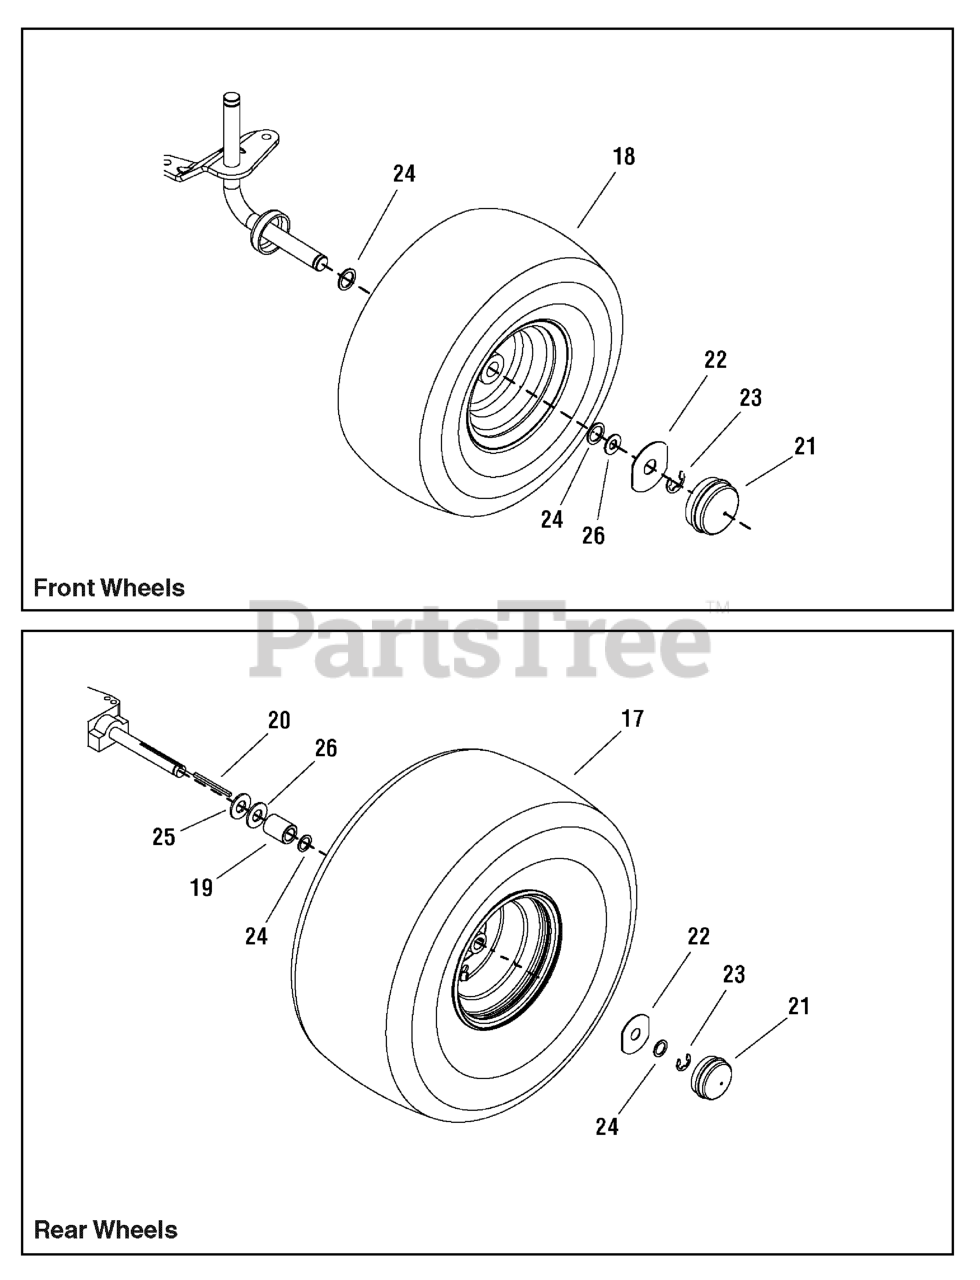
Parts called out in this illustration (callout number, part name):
17	WHEEL AND TIRE ASSEMBLY, Rear, 22 x 10 - 8
18	WHEEL AND TIRE ASSEMBLY, Front, 14.4 x 6
19	SPACER, Axle, Rear PM Hunter
20	KEY, Parallel PLN .187 x .187 x 3.0 STL
22	WASHER, 2-1/2
23	RING, Klipring EXT For .75 Dia Shaft blk
24	WASHER, 3/4
25	WASHER, 3/4
26	WASHER, 3/4
